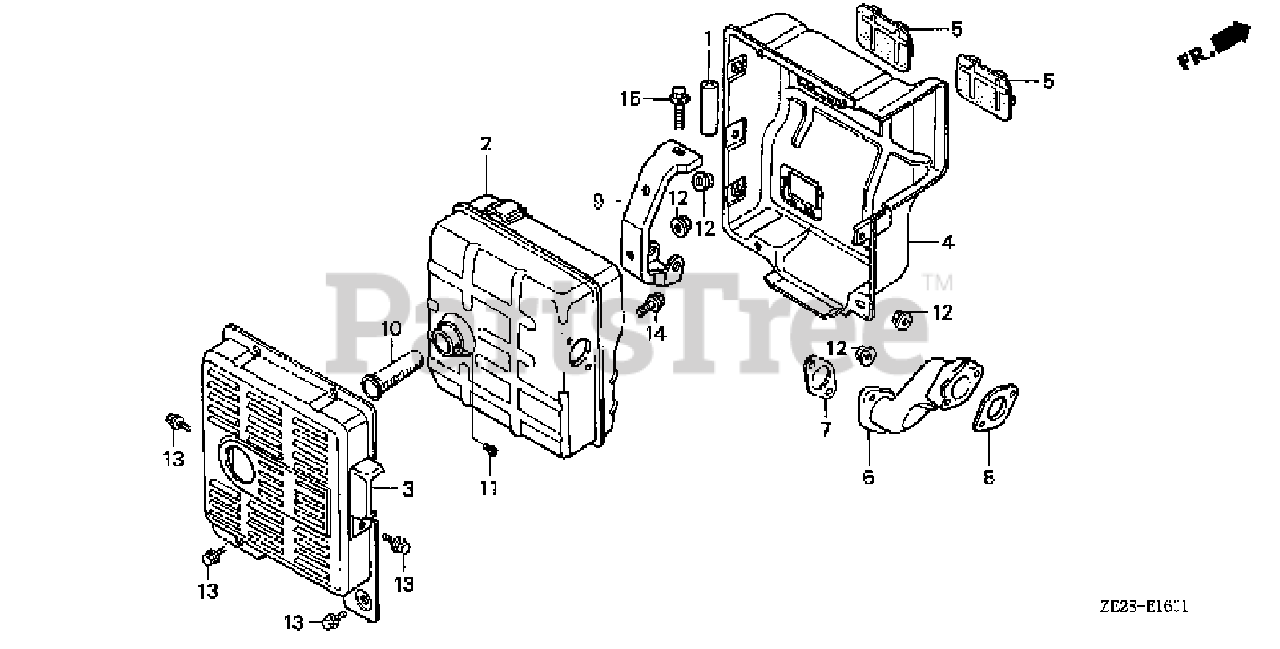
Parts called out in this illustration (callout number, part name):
1	COLLAR (10X16X53)
2	MUFFLER (TSURUMI)
3	PROTECTOR, MUFFLER (OUTER)
4	PROTECTOR, MUFFLER (INNER)
5	SEAL, MUFFLER PROTECTOR
6	PIPE, EX.
7	GASKET, EX. PIPE
8	GASKET, EX. PIPE
8	GASKET, EX. PIPE (WACKER)
9	STAY A, MUFFLER (TSURUMI)
10	ARRESTER, SPARK
11	SCREW, TAPPING (4X8)
12	NUT, FLANGE (8MM)
13	BOLT, FLANGE (6X10)
14	BOLT, FLANGE (8X20)
15	BOLT, FLANGE (8X70)
